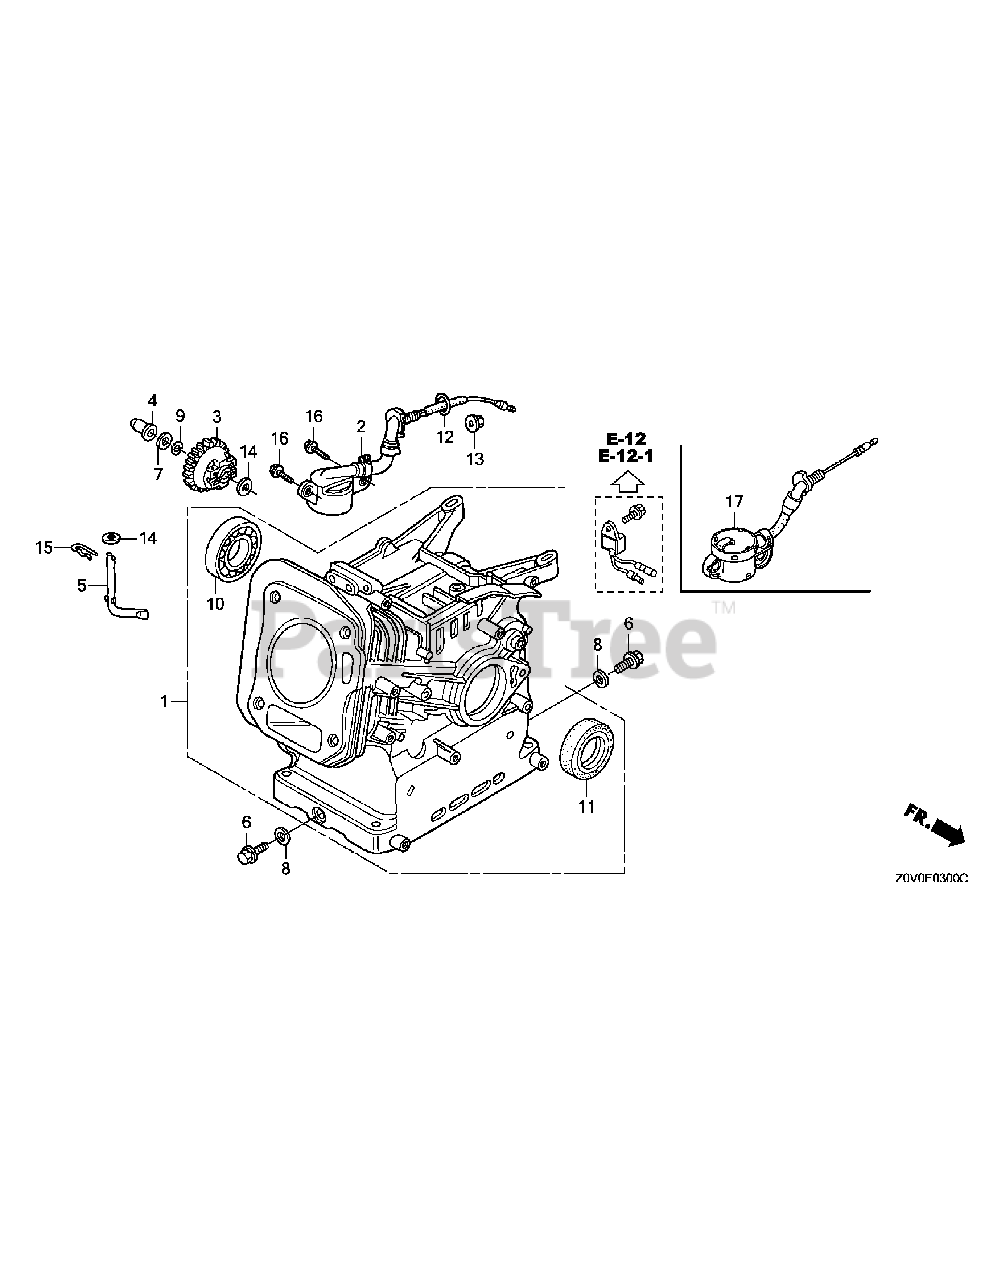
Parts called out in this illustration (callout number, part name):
1	Barrel Assy., Cylinder
2	Switch Assy., Oil Level
3	Governor Assy.
4	Slider, Governor
5	Shaft, Governor Arm
6	Bolt, Drain Plug
7	Washer, Thrust, 6Mm
8	Washer, Drain Plug, 10.2Mm
9	Clip, Governor Holder
10	Bearing, Radial Ball, 6205 (Nsk)
11	Oil Seal, 25X41X6
12	O-Ring, 14Mm(Nok)
13	Nut, Flange, 10Mm
14	Washer, Plain, 6Mm
15	Pin, Lock, 8Mm
16	Bolt, Flange, 6X12
17	Switch Assy., Oil Level
